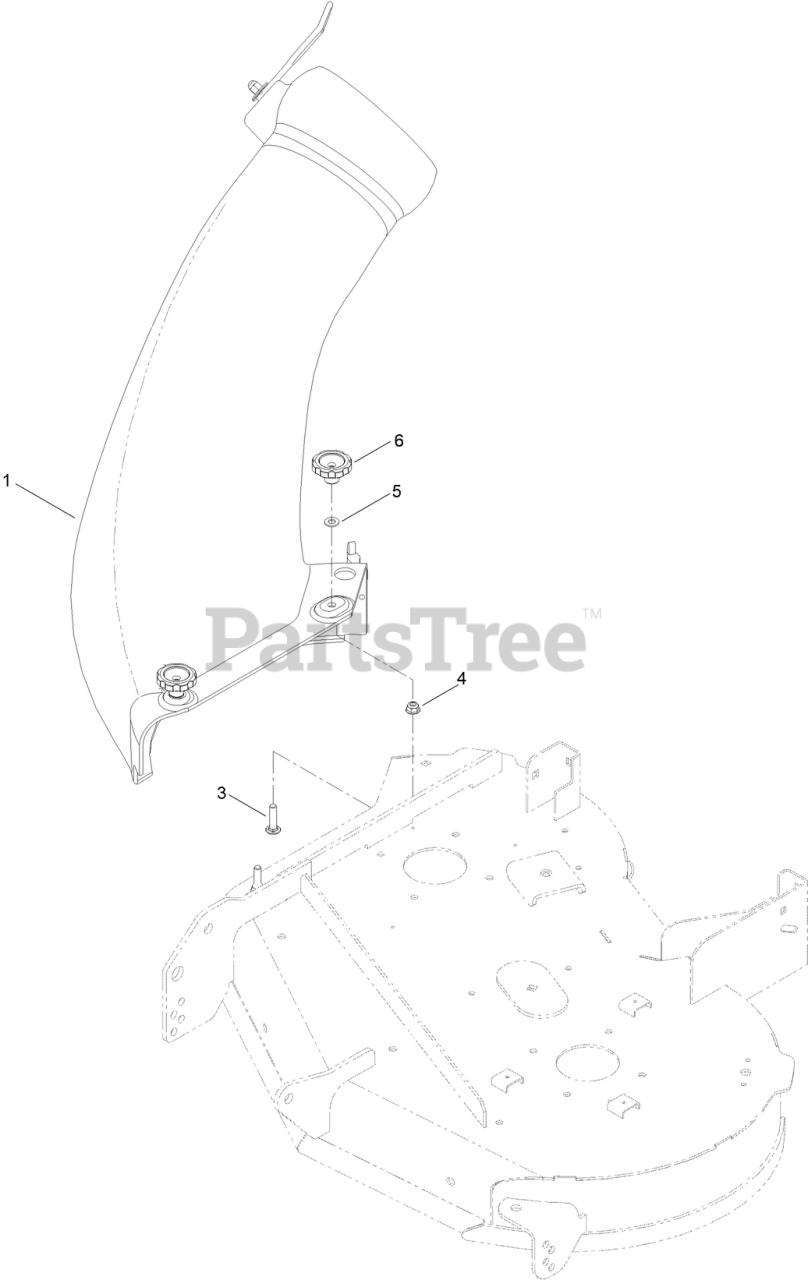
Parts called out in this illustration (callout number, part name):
1	34 INCH CHUTE ASM
3	SCREW-CARR
4	NUT-HF, NI
5	WASHER-PLAIN
